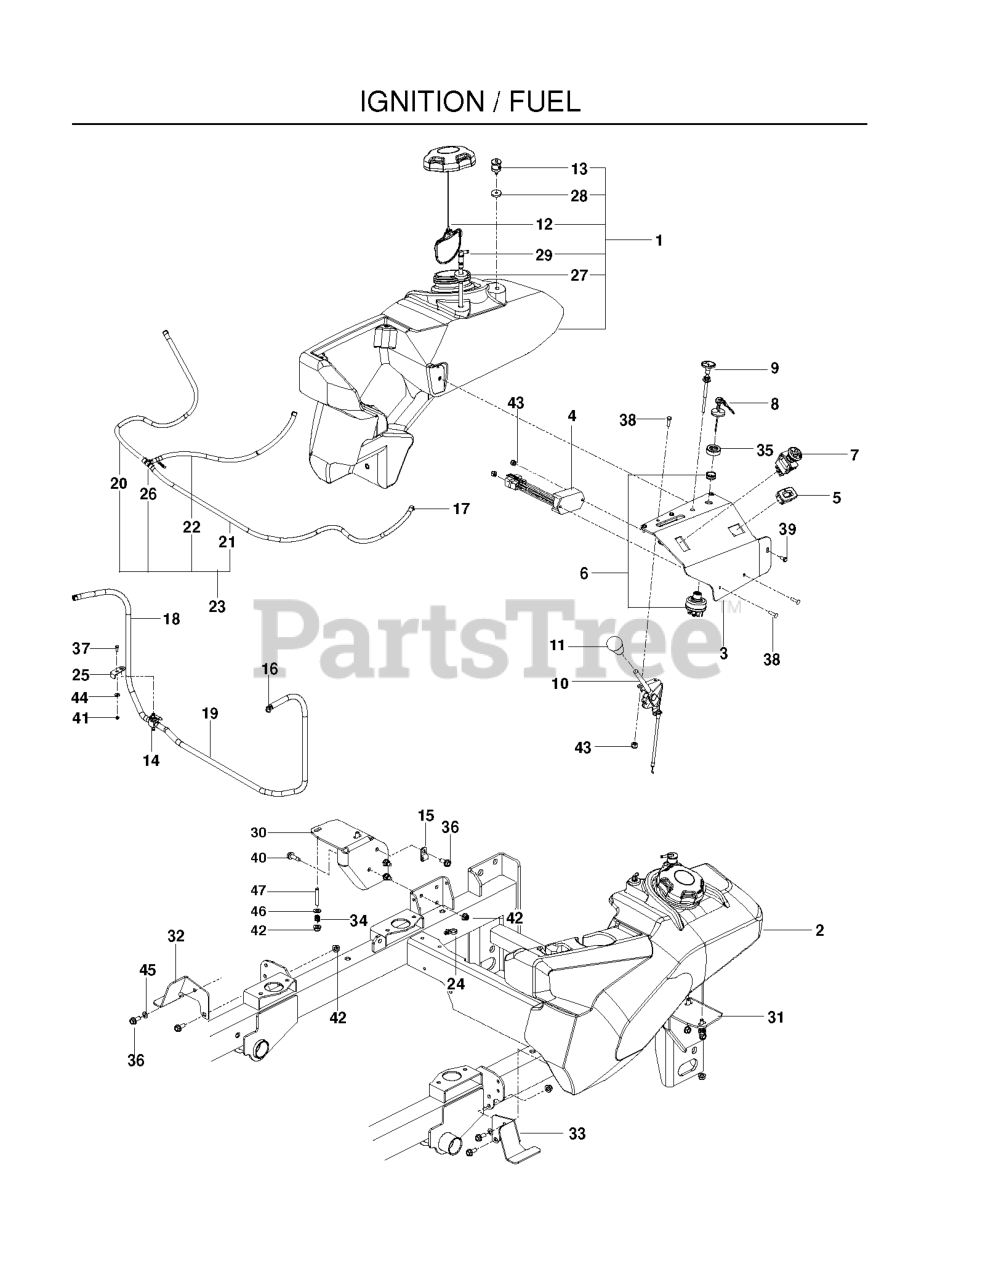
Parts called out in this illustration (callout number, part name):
1	RT FUEL TANK ASM EPA
2	LT FUEL TANK ASM EPA
3	PANEL.CONTROL.GAS.GRAY
4	TIMER, SEAT
5	HOUR METER
6	SWITCH, IGNITION, INDAK
7	SWITCH, PTO 10 AMP
8	KEY, IGNITION
9	CABLE, CHOKE, 48"
10	CABLE, THROTTLE, 46"
11	KNOB - SHIFT
12	CAP, FUEL
13	VALVE.FUEL.CHECK
14	FUEL VALVE
15	DOUBLE TUBE CLAMP
16	HOSE CLAMP
17	CLAMP, HOSE
18	LINE, FUEL, 22"
19	LINE, FUEL, 38"
20	HOSE, 3/16" VAPOR, 21"
21	HOSE, VAPOR 3/16 X 39"
24	TIE WRAP, 8-3/8", W/CLIP
25	BRACKET,FUEL VALVE, BLACK
26	TEE, FUEL LINE 3/16"
27	RUBBER GROMMET
28	GROMMET, CHECK VALVE
29	FITTING, FUEL
30	MOUNT, RT TANK, BLK
31	MOUNT, LT TANK, BLK
32	XX MOUNT, TANK, RT-BLK
33	MOUNT, TANK, LT-BLK
35	CAP IGNITION NUT
36	HHFS 5/16-18 X 3/4
37	HCS 1/4C X 3/4 HCS
38	SCR #10-24 X .75 SKT HD BLK
39	SCR #10-24 X 3/8 SKT HD BLK OX
40	RP BLT 5/16-18 X 1 THRD FORM D
41	JAM NUT 1/4C (2 2 PW01)
42	5/16-18 NYLOC FLANGE NUT
43	NUT 10-24 NYLOC
44	WASHER 1/4 FLAT
45	WASH 5/16 DISC SPRING ZD
46	FLAT WASHER 5/16 SAE
47	STUD, 5/16C
